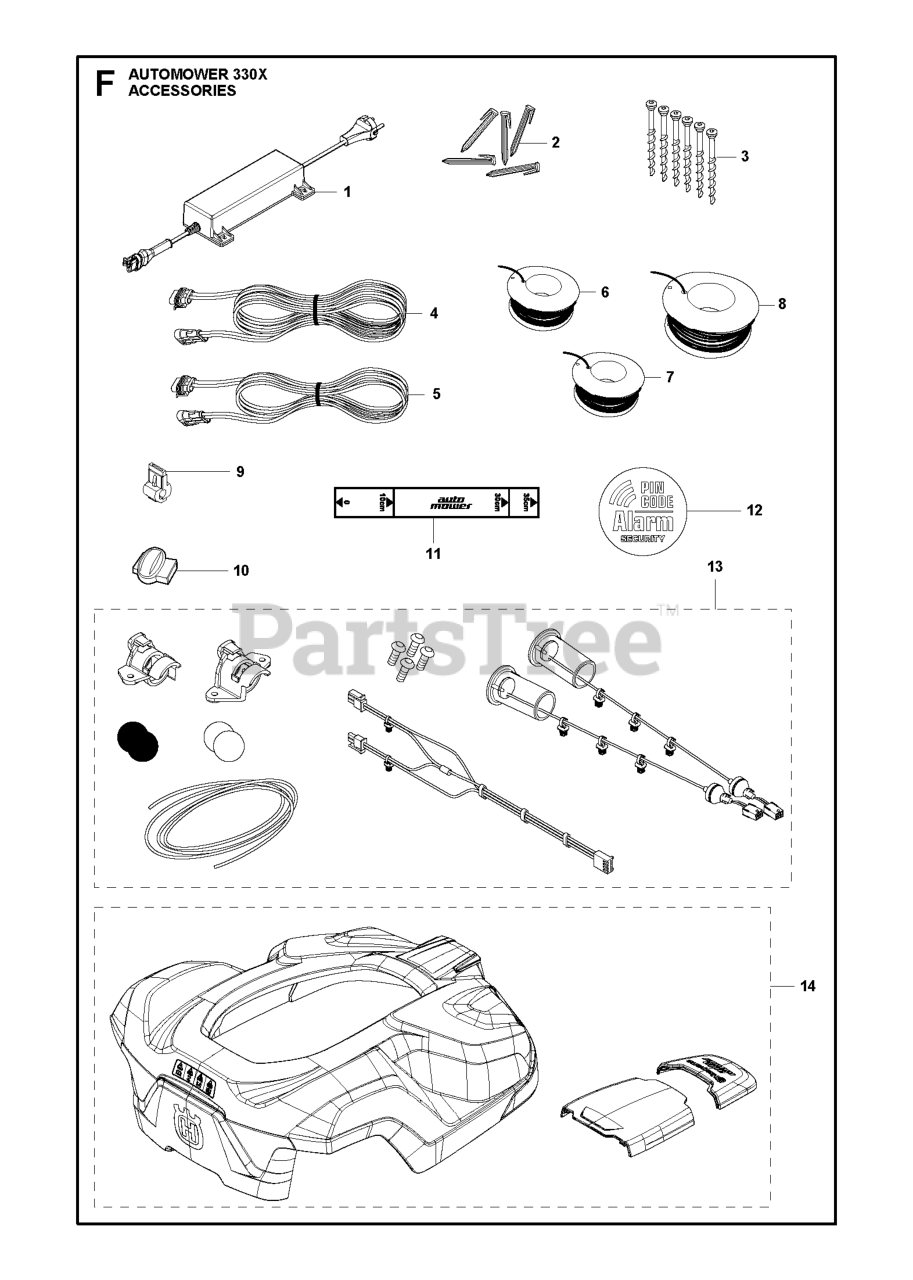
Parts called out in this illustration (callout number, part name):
2	BLADE KIT HUSQVARNA 9 PCS 50HR
2	BLADE SET 45 PCS
2	BLADE SET 300 PCS. CARBON STEE
3	DVD AUTOCHECK EXP SERVICE
4	LABEL WARRANTY SEAL DEALER
4	LABEL WARRANTY SEAL KIT 10 PK
5	TEST EQUIPMENT
6	CABLE WHITE ALT GREY
9	STICKER CABLE MARKERS KIT 10PC
14	REAR WHEEL KIT W/ BRUSHES
16	DECAL.HUSQVARNA.210MM
17	KIT LID - AUTOMOWER HOUSE
18	COVER BASE P2 HOUSE
20	HANDLE RELEASE LEFT
23	SPRING SPRING CAP
25	SCREW 14MM
27	HANDLE RELEASE RIGHT
28	SUPPORT BASE LEFT
30	SUPPORT BASE RIGHT
31	SCREW IHPANM M6X25 4.6 ZP-BC
32	430/450 HOUSE KIT
34	SCREW 14MM
